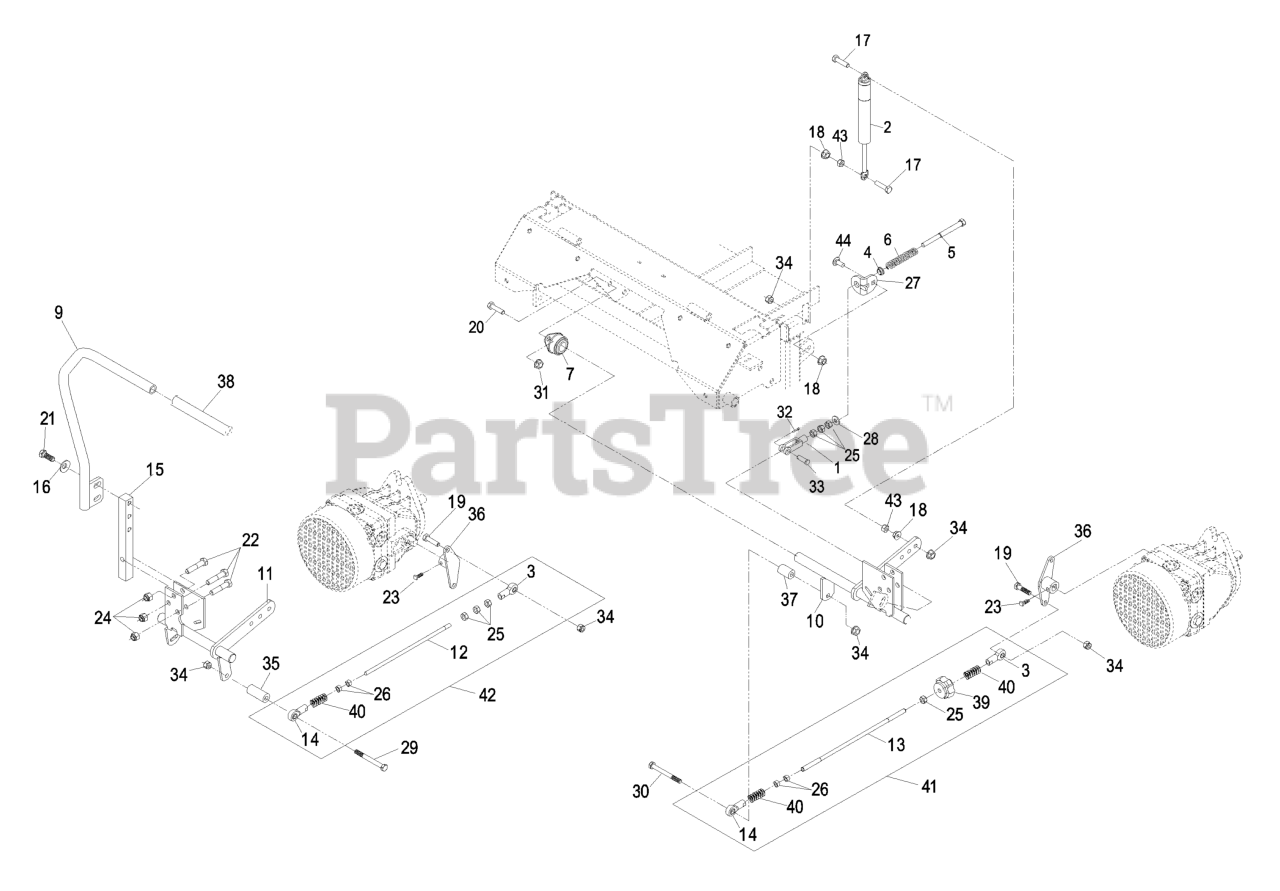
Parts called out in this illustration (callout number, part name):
1	YOKE-ADJUSTABLE
2	DAMPER-CONTROL, MOTION
3	BALLJOINT-RH
4	BUSHING-NYLON, FLANGED
5	BOLT-RETURN, NEUTRAL
6	SPRING-RETURN, NEUTRAL
7	BEARING-FLANGE, SIDE
9	RH MOTION CONTROL ASM
11	CONTROL-MOTION, RH
12	LINK,XP HYDRO CONNECT RH
13	LINK,TRACKING ROD XP
14	BALLJOINT-LH
15	ARM-SHAFT, CONTROL
16	WASHER-BELLEVILLE
17	SCREW-HH
19	SCREW-HH
20	SCREW-HH
21	SCREW-HH
22	SCREW-HH
23	SCREW-SET
24	NUT-LOCK, NI
25	NUT-HEX
27	TAB-ADJUSTMENT
28	WASHER-FLAT
29	SCREW-HH
30	SCREW-HH
31	NUT-HHF, WHIZ
32	PIN-COTTER
33	PIN-CLEVIS
34	NUT-LOCK, NI
35	SPACER-CONTROL, HYD
36	ARM-CONTROL, HYDRO
37	SPACER-HYDRO CONTROL, LH
38	GRIP,CONTROL LEVER
39	KNOB-TRACKING
40	SPRING-COMPRESSION
41	TRACKING ROD ASM
42	RH HYD CONNECT LINK ASM
43	NUT-HEX
44	SCREW-CARR
